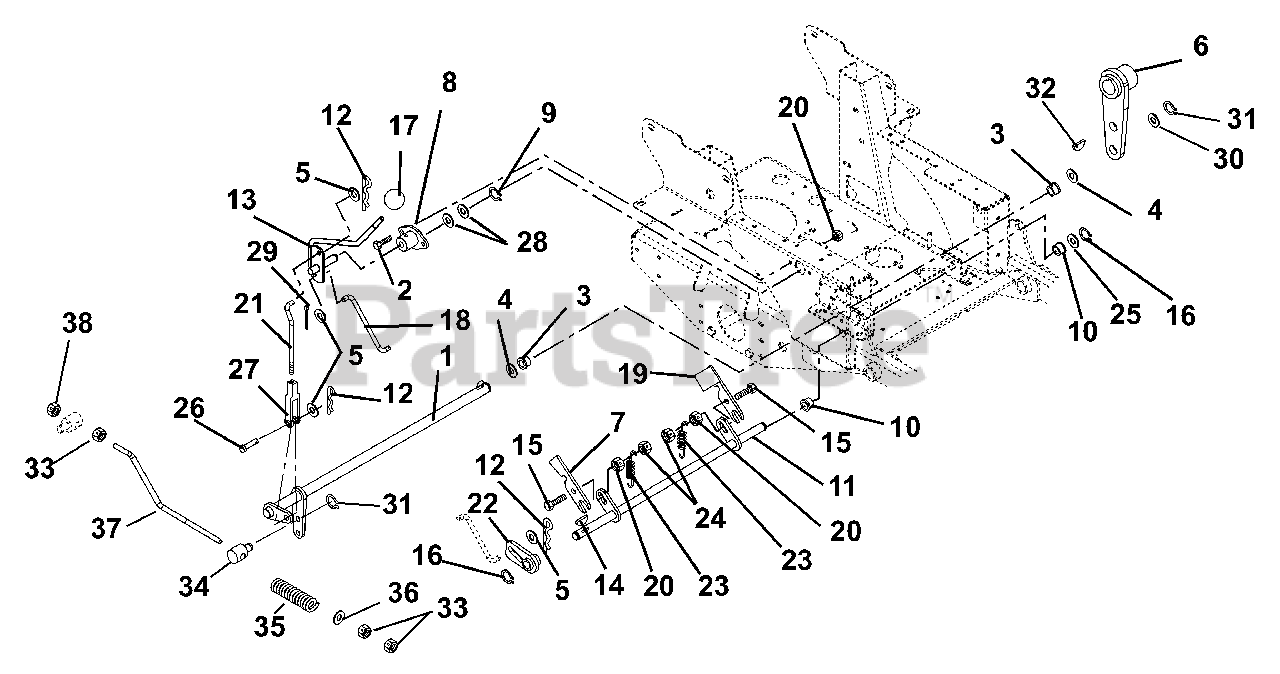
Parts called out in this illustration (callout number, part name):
1	Weldment, Brake Pivot
2	Bolt, Hex .31-18 x 1.00 Grade 5
3	Bushing, Flange .762 x 1.00 x .58 x 1.48 Nylon
4	Washer, Flat Steel .812 x 1.50 x .135
5	Washer, Flat Steel .406 x .812 x .065
6	Weldment, Brake Arm
7	Slide, Interlocking Brake
8	Bushing, Flange
9	Ring, Retaining External .625 x .05
10	Bushing, Flange .50 x .75 x .75 x 1.00
11	Weldment, Mechanical Brake
12	Pin, Hair
13	Weldment, Brake Actuating
14	Key, Woodruff .13 x .63
15	Bolt, Round Head Square Neck .31-18 x 1.25 Grade 5
16	Ring, Retaining External .50 x .05
17	Knob, Steering Lock
18	Linkage, Brake Actuating
19	Interlock, Safety Switch
20	Nut, Nyloc Flange 5/16-18
21	Linkage, Brake Compact-Z
22	Weldment, Parking Brake Hub
23	Spring, Tension .061 x .50 x 3.0
24	Nut, Locking Center .31-18
25	Washer, Flat Steel .505 x 1.00 x .062
26	Pin, Clevis .38 x 1.25
27	Clevis,.38-24 Adjustable
28	Washer-Flat-Steel .630 x 1.250 x .062
29	Pin, Cotter .09 x .75 Extended Prong Square Cut
30	Washer-Flat-Steel .755 x 1.375 x .062
31	Ring, Retaining External .689 x .077
32	Key-Woodruff .19 x .75
33	Nut, Jam .375-24
34	Pin, Pivot
35	Spring, Compression .143 x .710 x 2.00
36	Washer, Flat Steel .406 x .812, .065
37	Linkage, Brake
38	Nut, Locking Center .375-24
